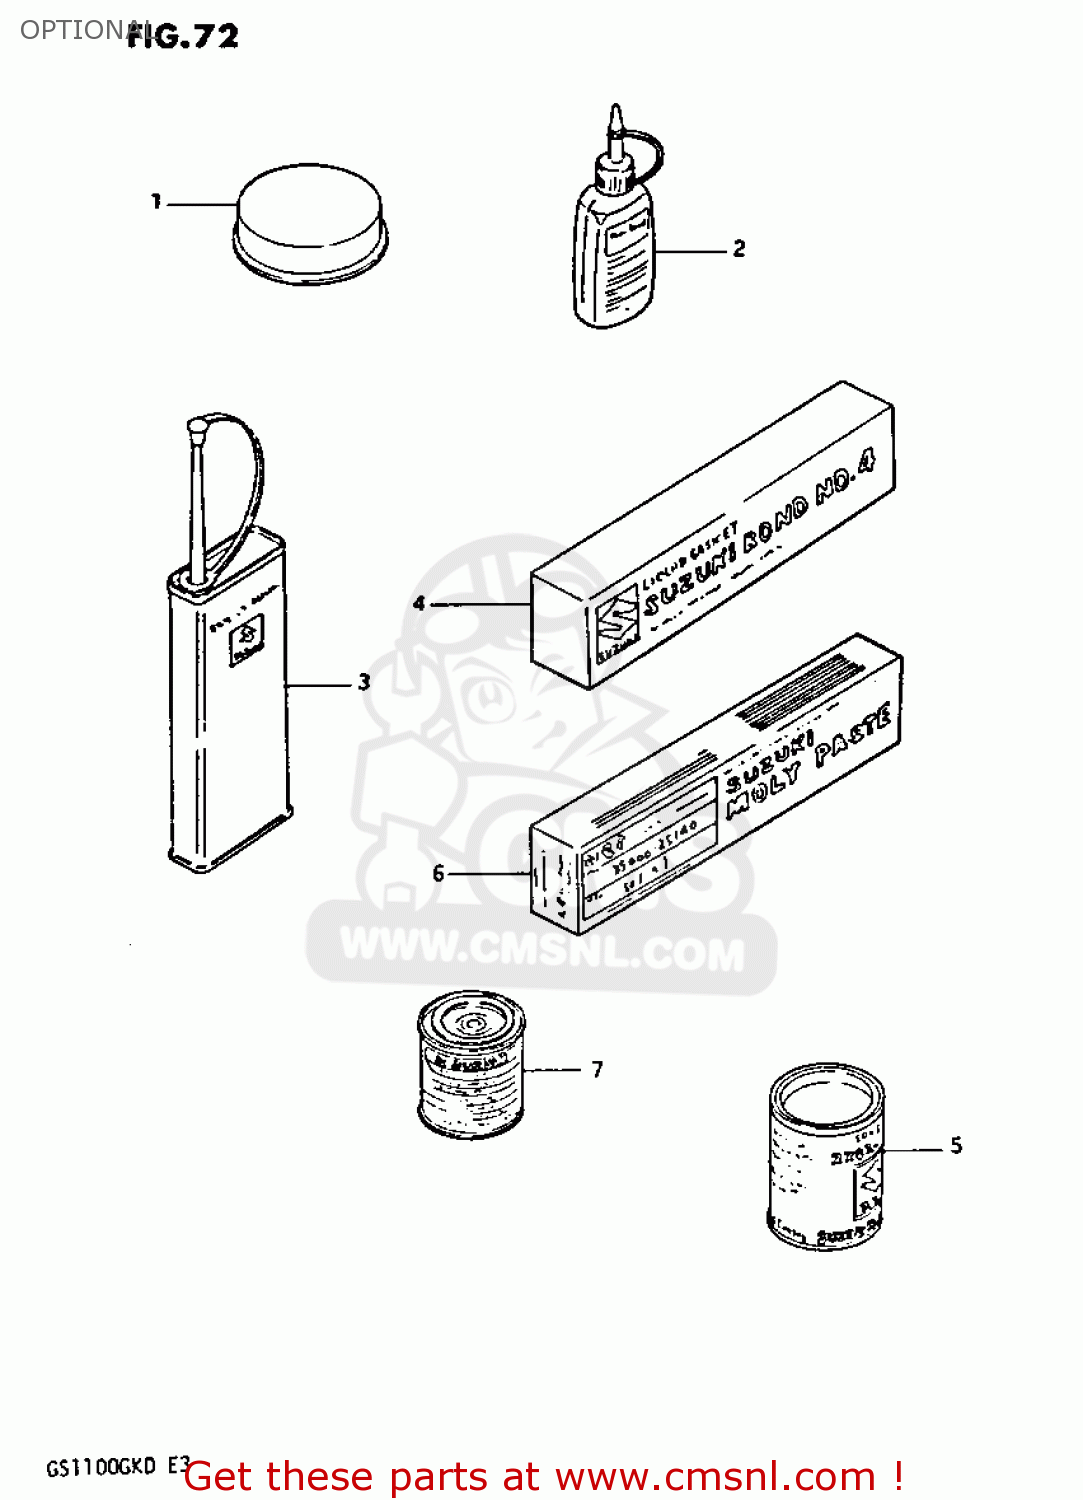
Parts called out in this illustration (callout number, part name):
1	GREASE,PBC FOR BRK PAD 20G
2	THREAD LOCK NO.1342
3	THREAD LOCK NO.1401 CLEAR 200G
4	LIQUID GASKET 1
5	GREASE(C)EP2 LITHIUM 150G
6	SUZUKI MOLY PASTE
7	PAINT,BLACK
